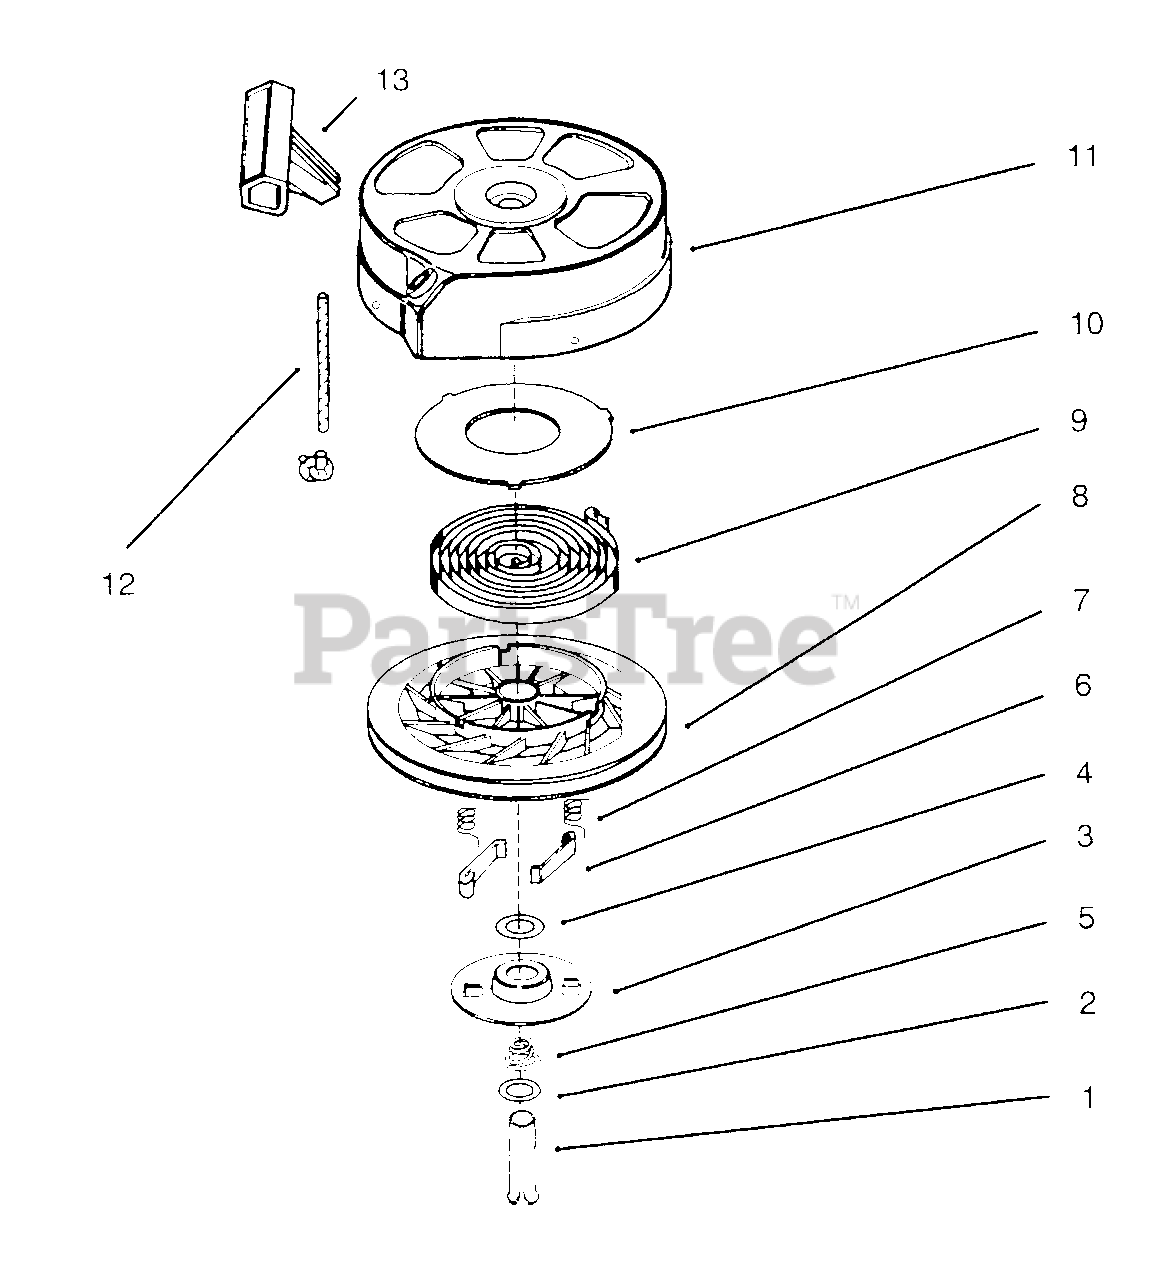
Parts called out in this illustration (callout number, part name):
1	Spring Pin (Incl. 4)
3	Retainer
5	Brake Spring
6	Starter Dog
7	Dog Spring
8	Pulley Ass'y (Incl. 9 & 10)
9	Rewind Spring
10	Spring Cover
11	Starter Housing Ass'y (40 degree grommet)
12	Starter Rope (Length 98" x 9/64" dia.)
13	Starter Handle
